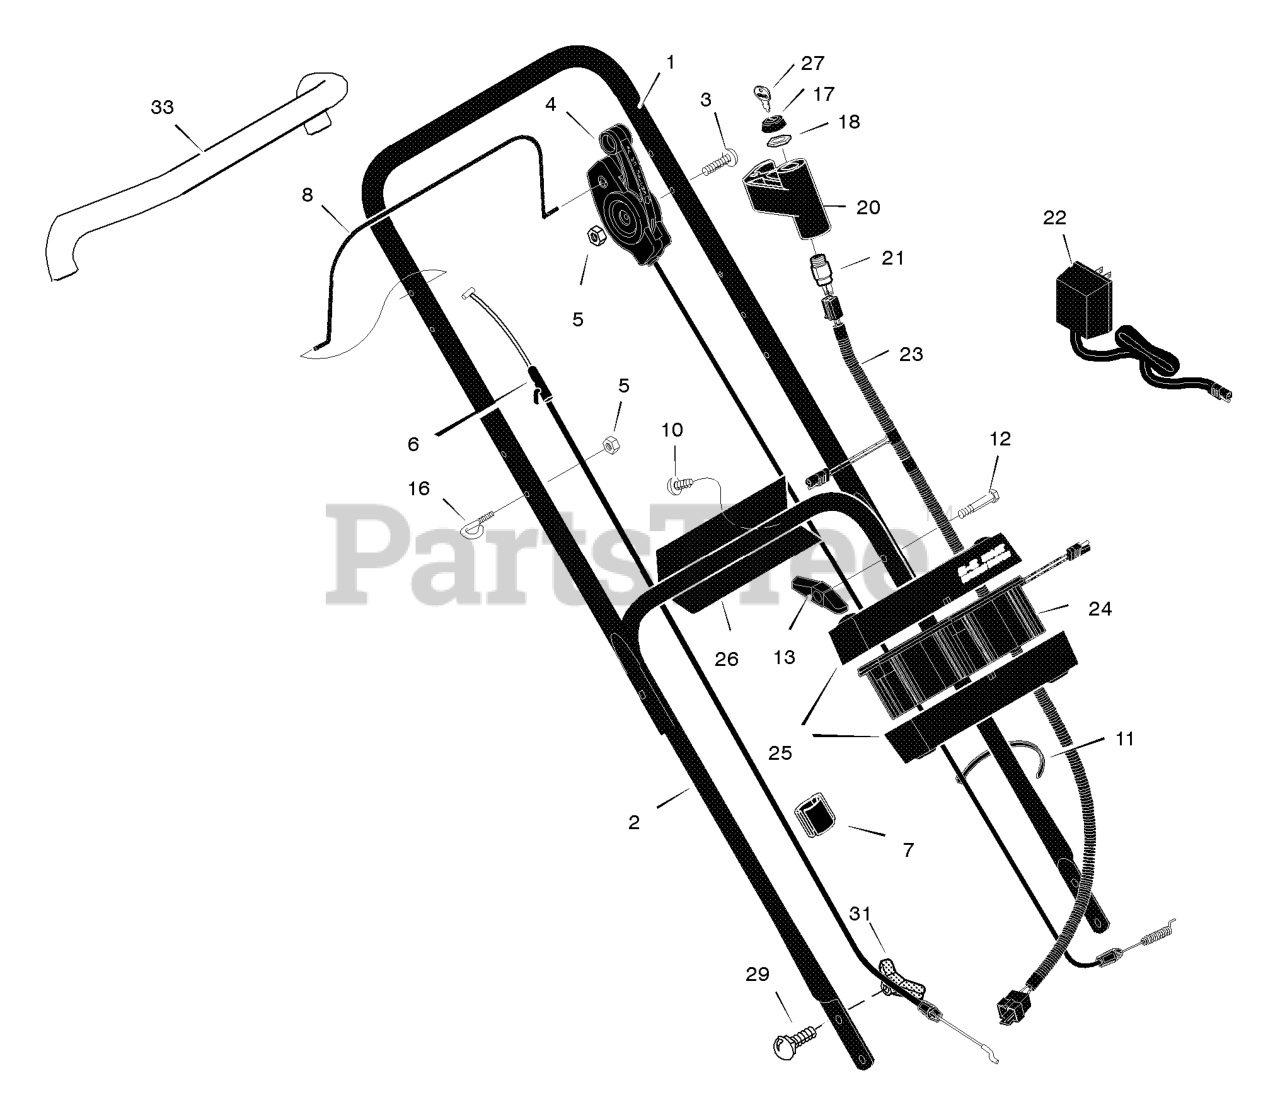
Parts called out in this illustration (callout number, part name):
1	Handle, Upper (Black)
2	Handle, Lower (Black)
4	Control, Drive
5	Locknut
6	Cable, Stop (Briggs)
7	Fastener, Double Cable
8	Lever, Stop
11	Fastener, Cable
13	Knob
16	Guide, Rope
17	Cap
18	Nut
20	Cover, Ignition
21	Switch Ignition & Key
22	Charger, Battery
23	Harness, Wiring
24	Battery
25	Case, Battery
26	Bracket, Battery
27	Key, Ignition
29	Bolt, Carriage
31	Knob, Plastic
33	Tubing, Foam
